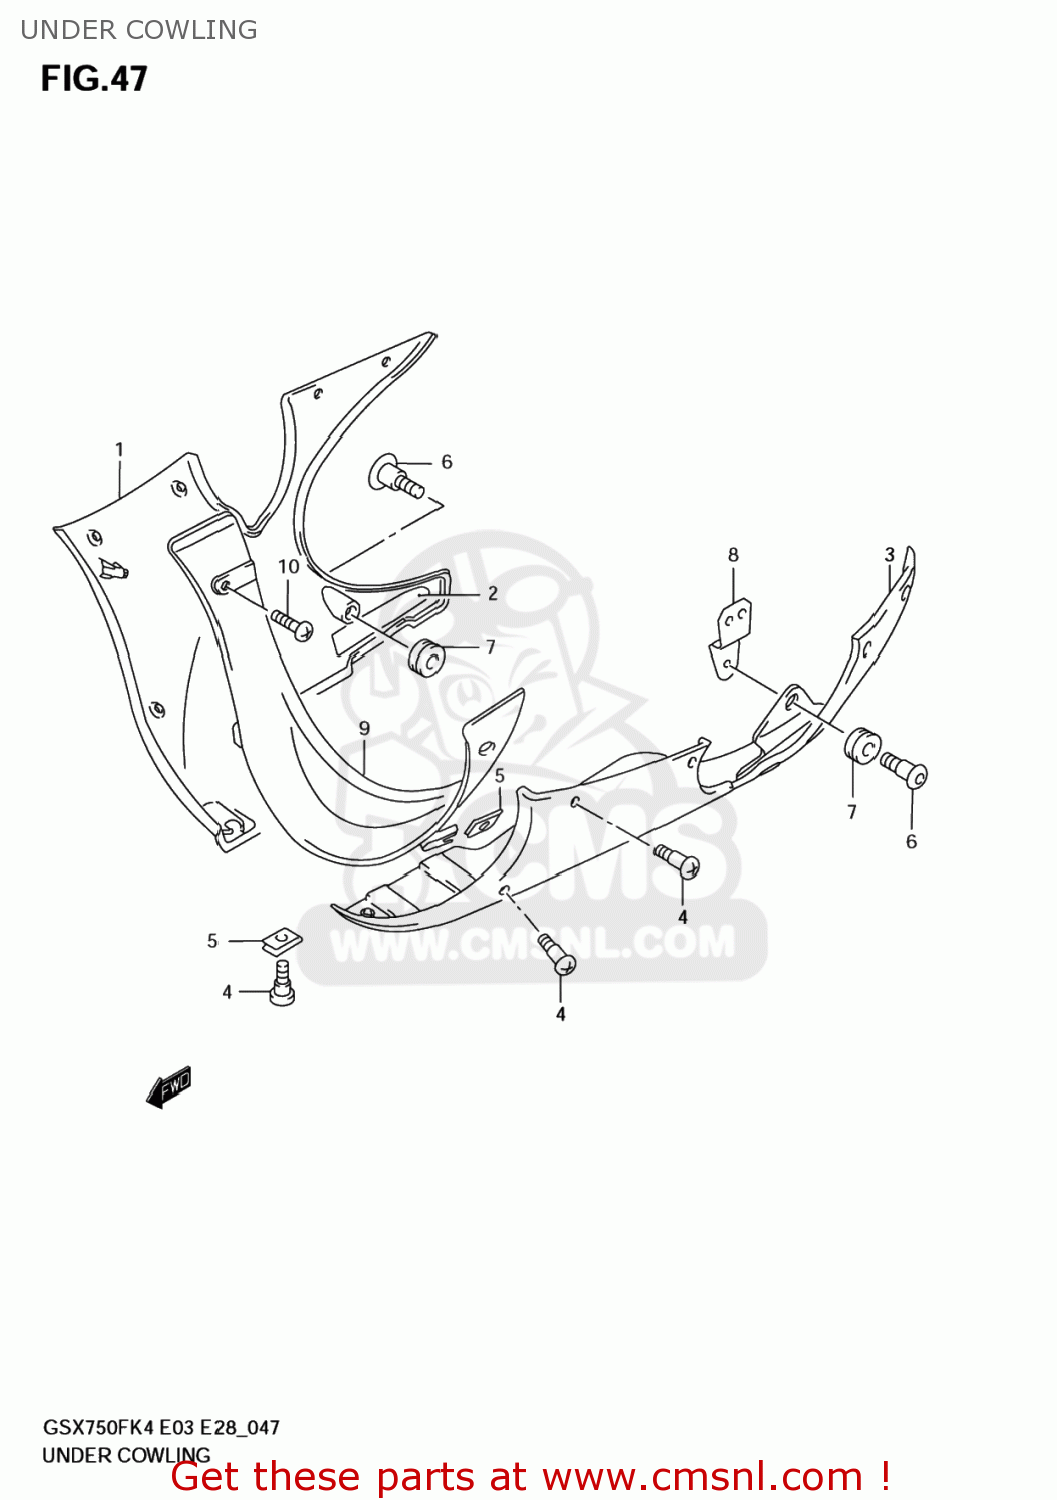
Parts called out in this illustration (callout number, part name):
1	COWLING,UNDER,R(SILVER)
2	SHIELD,COWLING UNDER,R NO.1
3	COWLING,UNDER,L
4	SCREW(5X16)
5	NUT,COWL
6	SCREW(6X20)
7	CUSHION
8	BRACKET,UNDER COWL,L & FRAME
9	COWLING,UNDER CTR
10	SCREW
